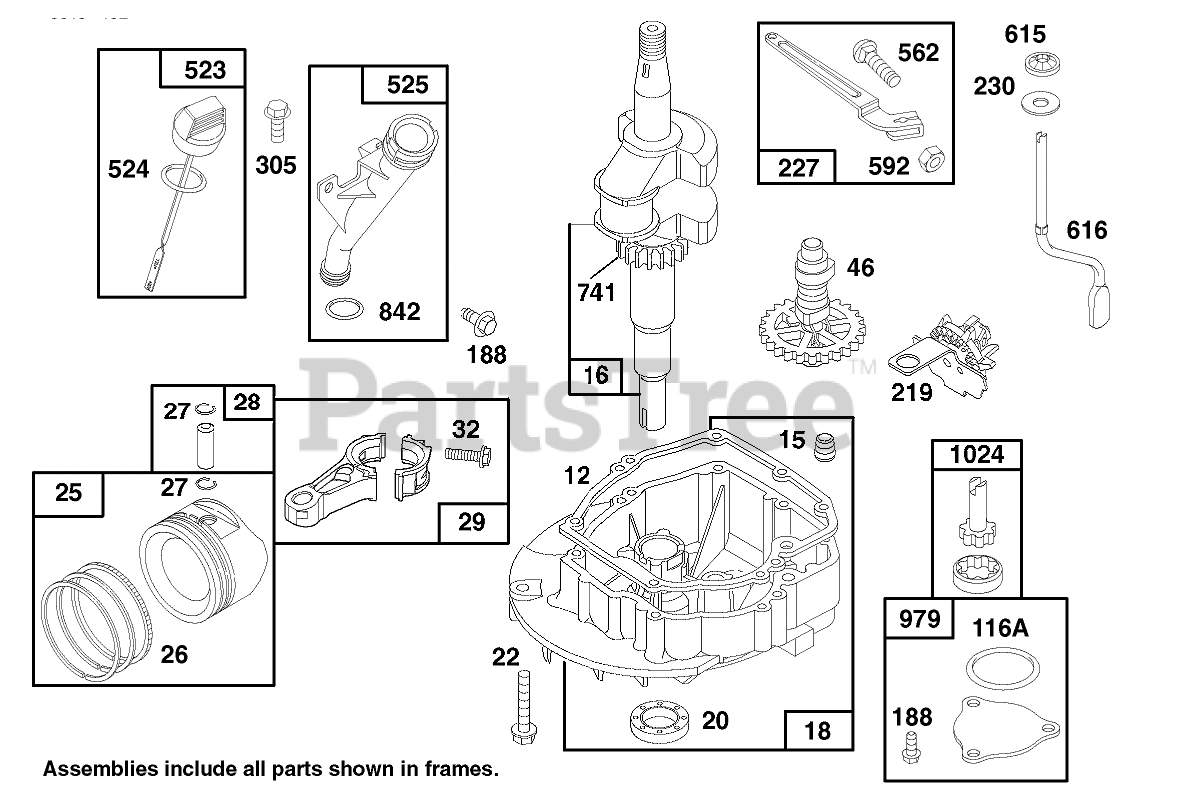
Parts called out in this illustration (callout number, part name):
12	ENGINE BASE GASKET
15	Plug-Pipe
16	CRANKSHAFT
18	ENGINE SUMP
20	SEAL-OIL
22	SCREW - ENGINE BASE
25	STD PISTON ASSEMBLY
26	STD RING SET
27	PISTON PIN LOCK
28	PIN ASM - PISTON
29	STD PISTON ASSEMBLY
32	Connecting Rod
46	CAM GEAR
116A	O RING SEAL
188	SCREW - HEX HEAD
219	GOVERNOR/OIL SLINGER
227	GOVERNOR LEVER ASSEMBLY
230	WASHER
305	SCREW - HEX HEAD
523	DIPSTICK-OIL
524	O-RING
525	OIL FILLER TUBE
562	GOVERNOR LEVER BOLT
592	HEX NUT
615	FASTENER
616	GOVERNOR CRANK
741	TIMING GEAR
842	O-RING
979	OIL PUMP COVER
1024	OIL PUMP
